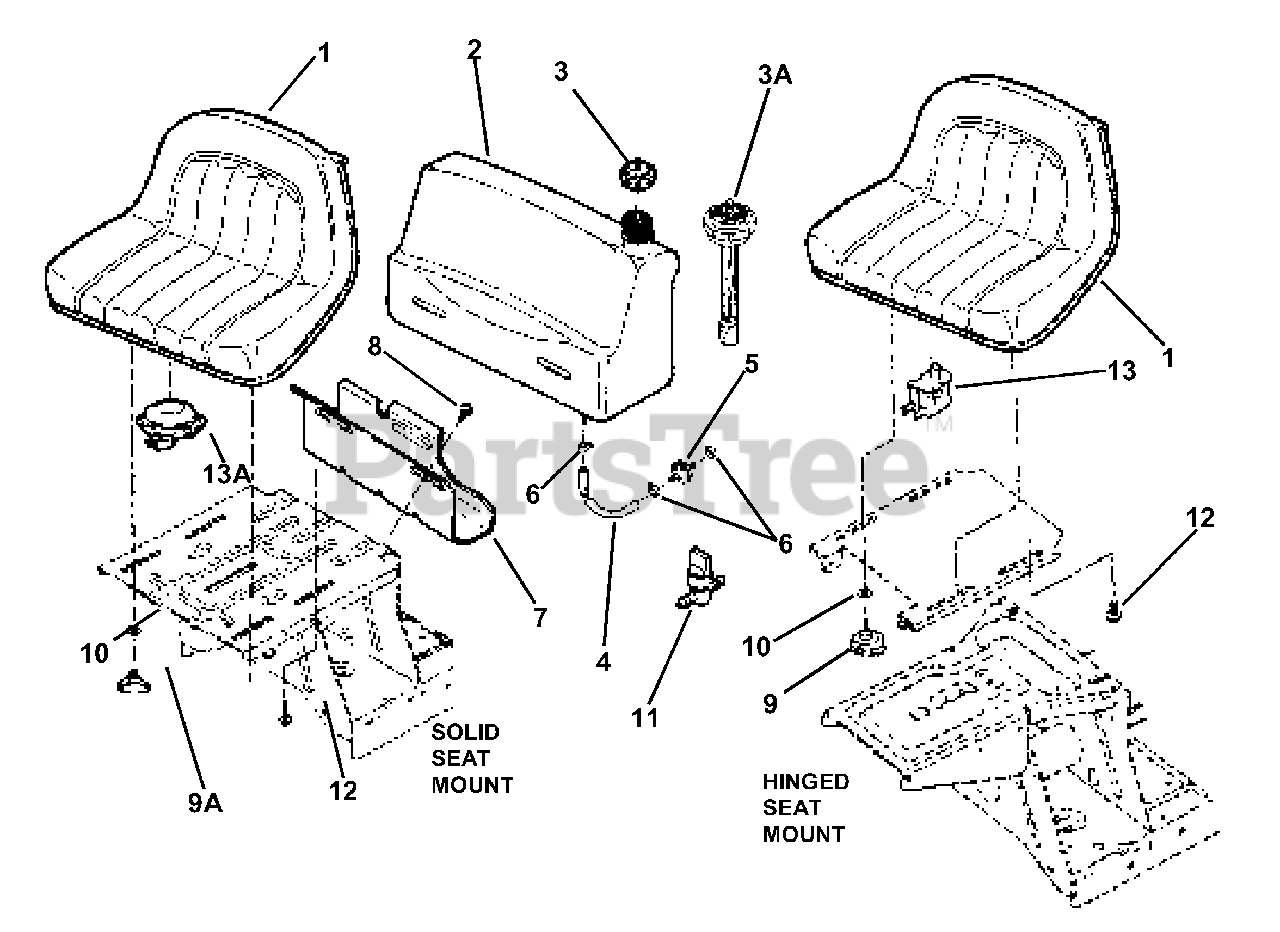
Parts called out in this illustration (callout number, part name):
1	SEAT, Operator
2	ASSEMBLY, Fuel Tank
3	CAP, Fuel Tank
3A	CAP, Fuel Tank with Gauge
4	HOSE, Fuel (7" Long)
5	FILTER, Fuel (In-Line)
6	CLAMP, Fuel Line
7	BRACKET, Fuel Tank (Rear)
8	SCREW, 5/16-18 x 5/8" Pan Head Torx Self-Tap
9	KNOB , Hinged Seat (Series 16 & 18)
9A	KNOB, Seat Adjusting
10	SPACER, 5/16 (33" Models)
11	VALVE, Fuel Shut-Off (Accessory)
12	BOLT, 5/16-18 x 1/2" Hex Flange Lock
13	SWITCH, Seat
13A	SWITCH, Seat
